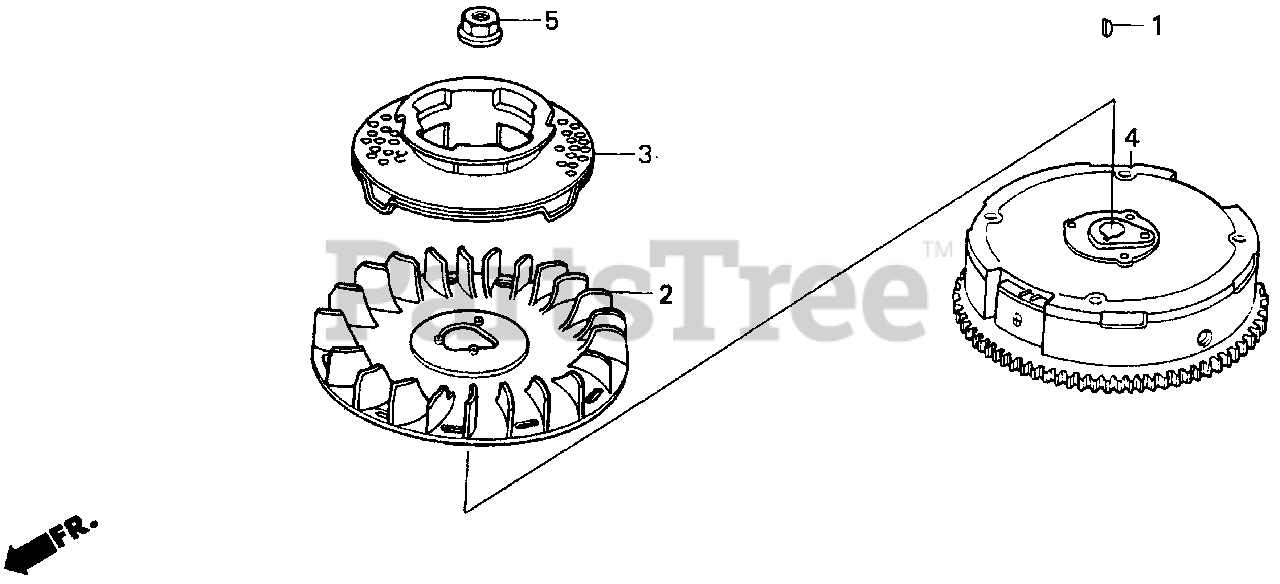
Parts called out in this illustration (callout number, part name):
1	KEY, SPECIAL WOODRUFF (25X18)
2	FAN, COOLING
3	PULLEY, STARTER
4	FLYWHEEL (STD)
5	NUT, SPECIAL (14MM)
